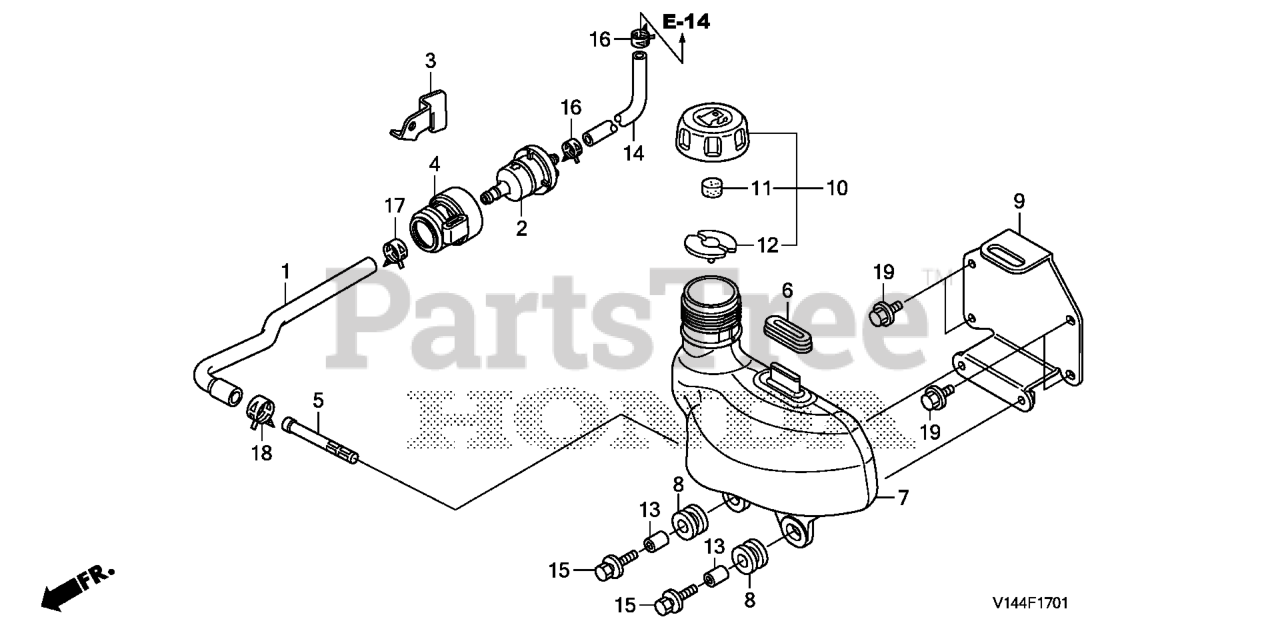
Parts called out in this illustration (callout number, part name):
1	TUBE A, FUEL (FKM)
2	FILTER, FUEL
3	STAY, FUEL STRAINER
4	SUSPENSION, STRAINER
5	BUSH, FUEL PURGE
6	RUBBER, TANK SETTING
7	TANK, FUEL
8	RUBBER B, TANK MOUNTING
9	BRACKET, FUEL TANK
10	CAP ASSY., FUEL TANK
11	SPONGE, FUEL CAP BREATHER
12	GASKET, FUEL CAP
13	COLLAR (14X6.1)
14	TUBE, FUEL (4.5X95)
15	BOLT-WASHER (6X25)
16	CLIP, TUBE (D8)
17	CLAMP, TUBE (D10)
18	CLAMP, TUBE (D12)
19	BOLT, FLANGE (6X12) Use from Engine SN 2086984.
